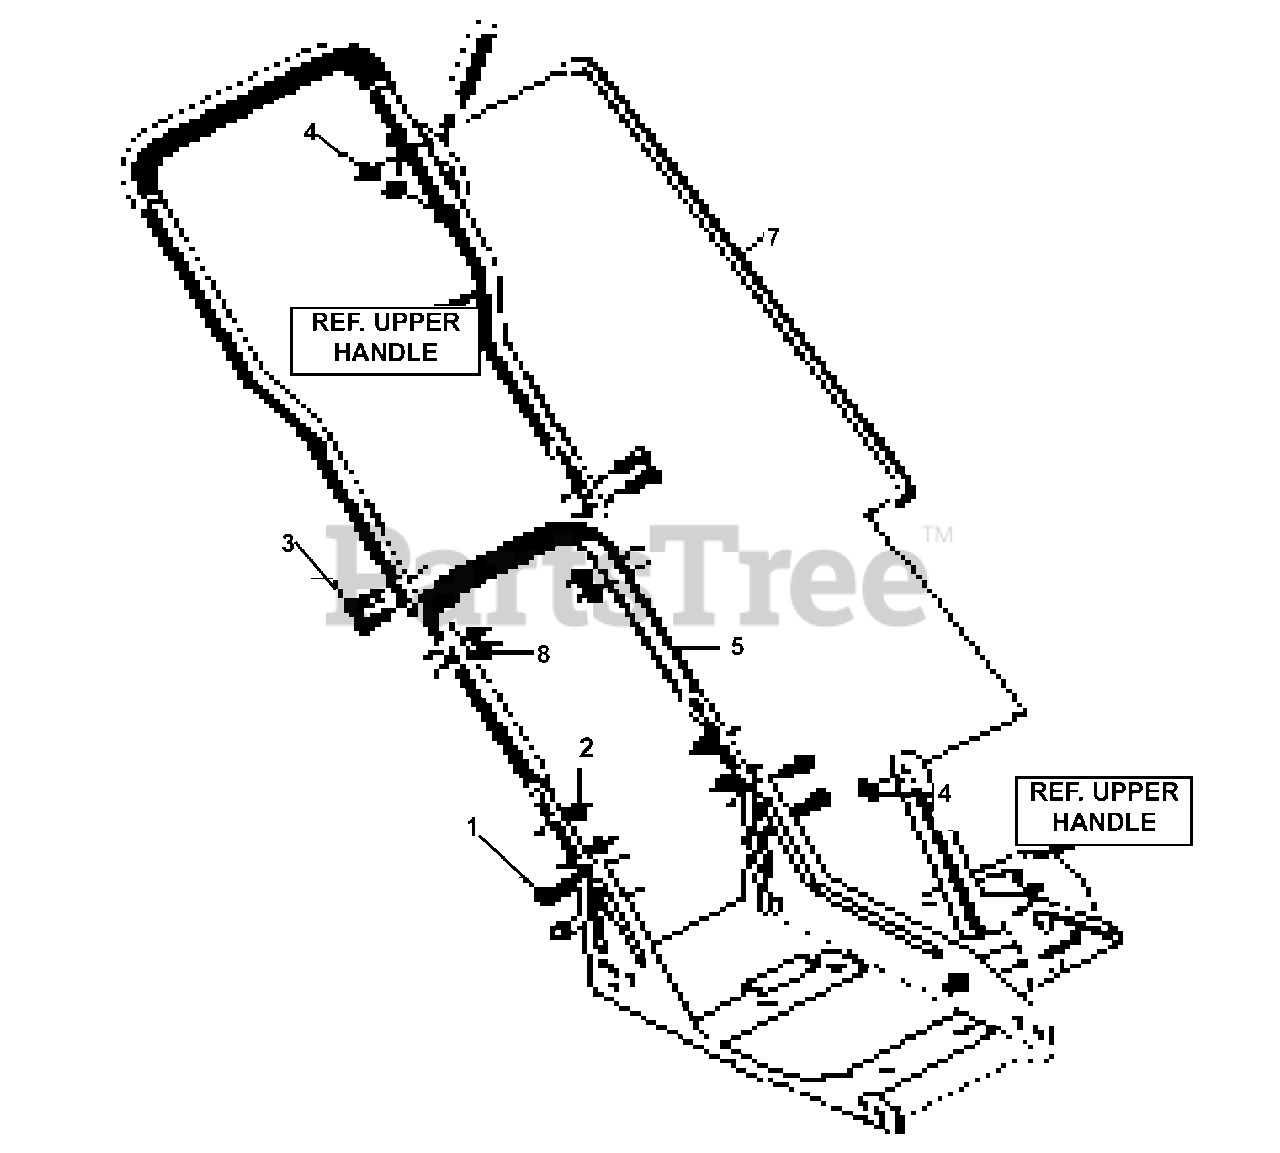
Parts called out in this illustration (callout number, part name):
1	Screw, 5/16-18x.63
2	Nut, 5/16-18 Reghexctrlk
3	Carr. Bolt, 5/16-18x1.63
4	Hair Pin .072Diax1.13Lg
5	Lower Handle
7	Control Rod
8	Nut, 5/16-18 Reghexctrlk
